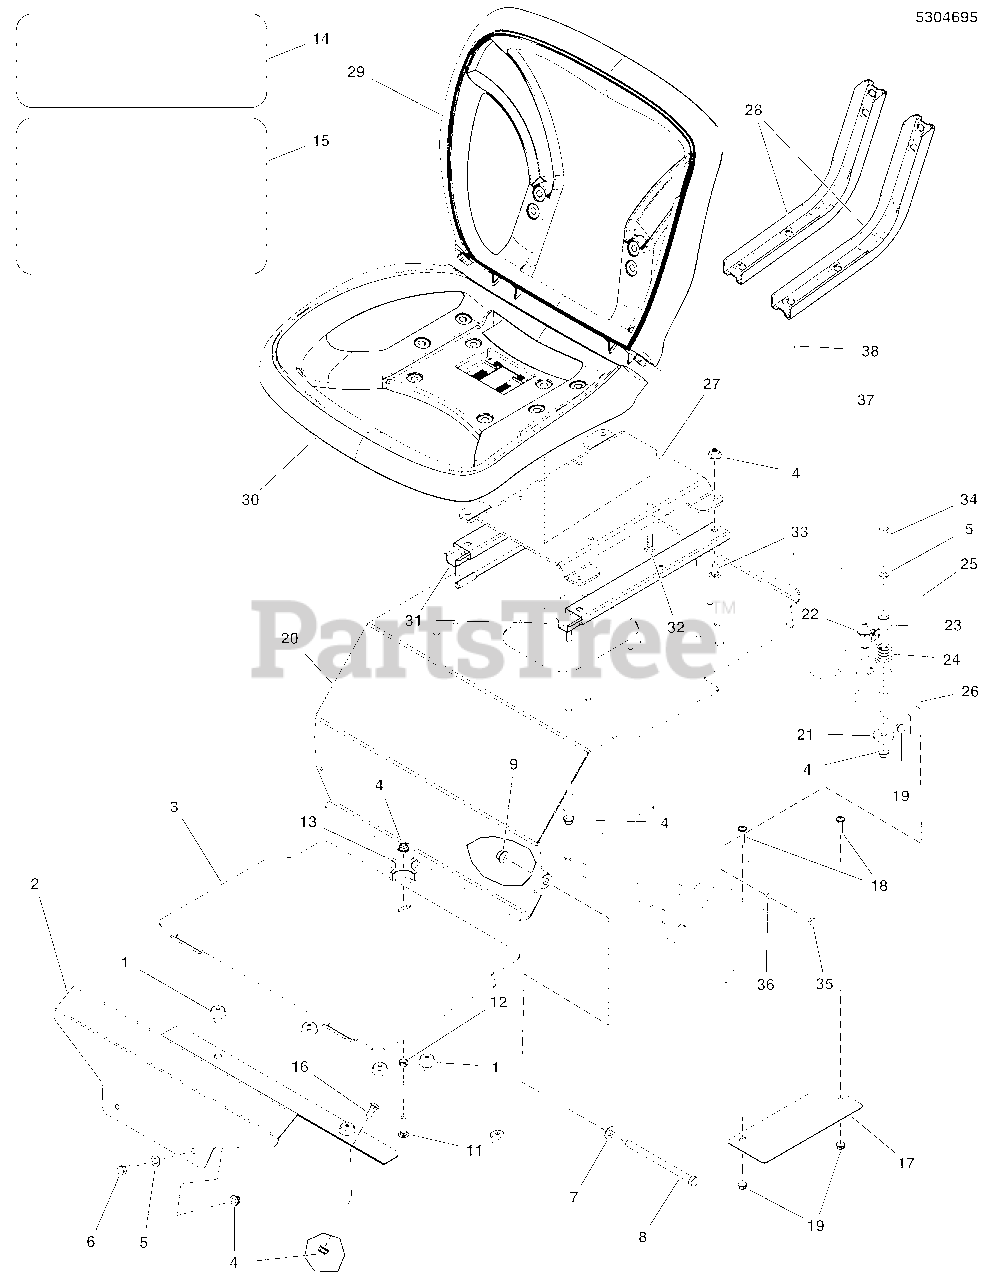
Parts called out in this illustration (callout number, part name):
1	MOUNT, Vibration
2	PLATE, FLOOR RIGID, S125XT - ORG
3	PLATE, FLOOR, REMOVABLE, IS700 - ORG
4	NUT, 5/16-18, Flange Nylock, GR F, Zinc/Clear
5	WASHER, Flat, 5/16
6	CAPSCREW, Hex Head, 5/16-18 X 1
7	WASHER, 3/8 (.406 X .816 X .65), Flat, Zinc/Clear
8	BOLT, 3/8-16 X 5-1/2 GD5 YZ
9	NUT, 3/8-16, Hex Flange Nylock
10	SPRING, SEAT SUPPORT
11	BOLT, 5/16-18 X 1-1/4, CARRIAGE, GD5, CZ
12	NUT, Hex Center Lock, 5/16-18, GRB
13	KNOB, Internal Thread, 5/16 (Used Only on 24 in. Models)
14	SAFETY WALK
15	SAFETY WALK, FLOOR PLATE, S50X, 10X17.13
16	BOLT, 5/16-18 X 3/4, CARRIAGE, GD5, CZ
17	PLATE, SEAT BELT GUARD - S125XT - BLK
18	CAPSCREW, Button Allen Head, 1/4-20 x 3/4
19	NUT, 1/4-20, GR5 Flanged Nylock, Zinc/Clear
20	ASSM, SEAT PLATE W/DECAL (5416034C)
21	WASHER, CLUTCH ANCHOR, 5/16
22	SWITCH, Seat, Push Button (NC) (gray)
23	SPACER, .33 X .66 X 1.31 SHLDR, CZ
24	SPRING COMP .76IDX1.3LGX.105WIRE BLACK
25	PLATE, SEAT SWITCH - ORG
26	WELD, OPERATOR PRESENCE - ORG
27	PLATE, SEAT MOUNT - CONTENDER - BLK
28	SUPPORT, Mesh Seat, R.H.
29	SEAT, Mesh Back
30	SEAT, Mesh Bottom
31	SLIDE-SEAT VIPER (2 PC SEAT)
32	SCREW, 5/16-18 X .750, Flanged Whiz-Lock, GR5
33	BOLT, Carriage, 5/16-18 X 3/4, GR5
34	BOLT, 5/16-18 X 2-1/4" GD5 YZ
35	BOLT, 1/4-20 X 1", GD
36	WASHER, 1/4, Flat, GR5 Zinc/Clear
37	SCREW, 5/16-18X.750 BUTTON HD PHOS&OIL
38	WASHER, Flat
